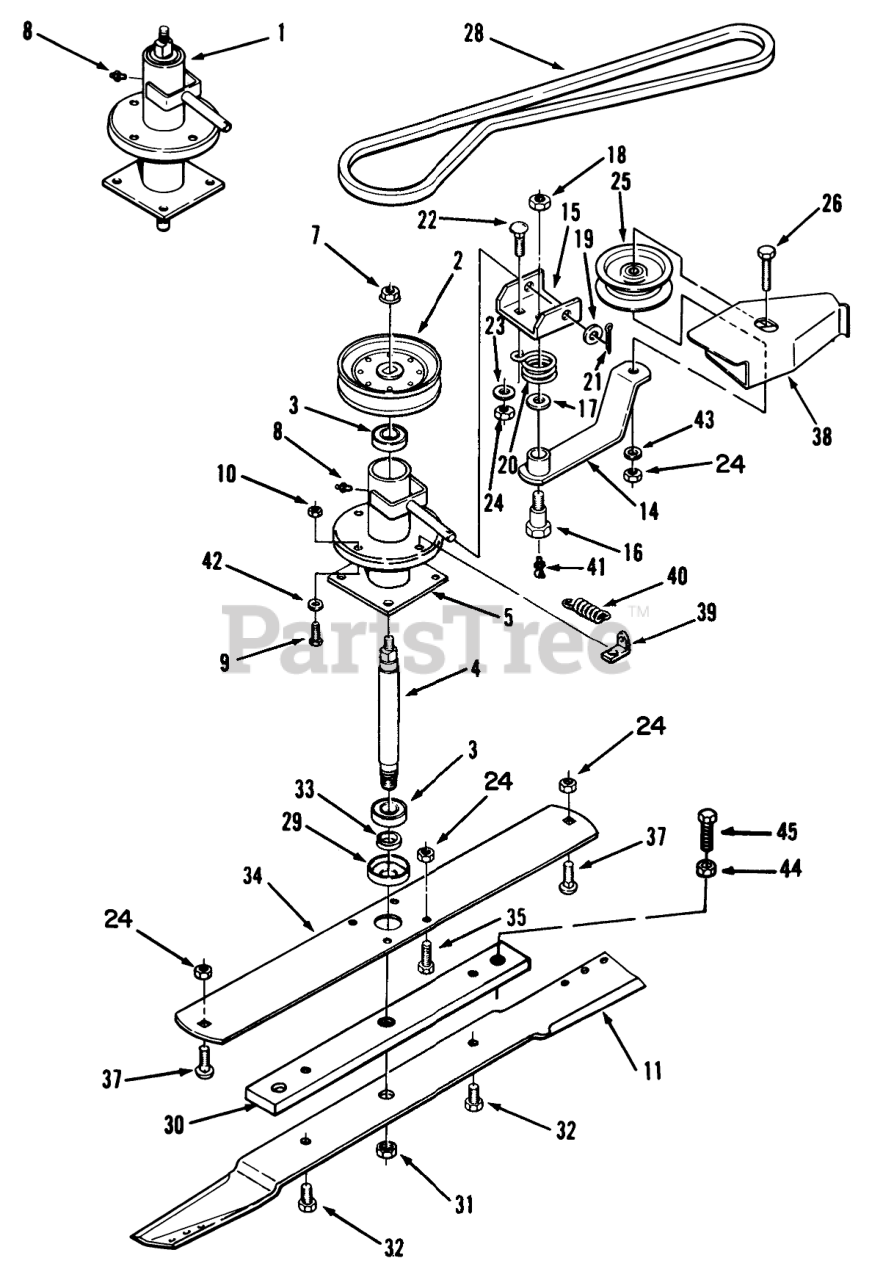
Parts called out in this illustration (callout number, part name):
1	Spindle Complete (Incl. Ref. #3, 4, 5 & 8)
2	PULLEY SPINDLE
3	BEARING-BALL
4	SHAFT SPINDLE
5	ASS'Y-BLADE HOUSI R
7	NUT 3/8-24 WHIZLOCK
8	FITTING-GREASE
9	SCREW-HH
10	WASHER-LOCK
11	S/A-30' BLADE ASM
14	ASSY LEVER R
15	CHANNEL PIVOT R
16	SHOULDER BOLT
17	WASHER-FLAT
18	NUT-JAM(7/16-14)
19	WASHER
20	SPRING-TORSION
21	PIN-COTTER
22	BOLT-CARR
23	WASHER-FLAT
24	NUT-LOCK, NI
25	PULLEY IDLER R
26	SCREW-HH
28	BELT-V, LOWER PTO
29	CUP SPINDLE
30	BAR-BLADE R
31	NUT-JAM
32	HEX BOLT 1/2-13X3/4
33	SPACER-BLADE
34	PLATE SUPPORT R
35	SCREW-HH
37	SCREW-CARR
38	COVER BELT R
39	CLIP - SPRING
40	SPRING-EXTENSION
41	FITTING-GREASE, 90 DEG
42	WASHER-LOCK
43	WASHER
44	NUT-HEX, JAM
45	SCREW-HH
